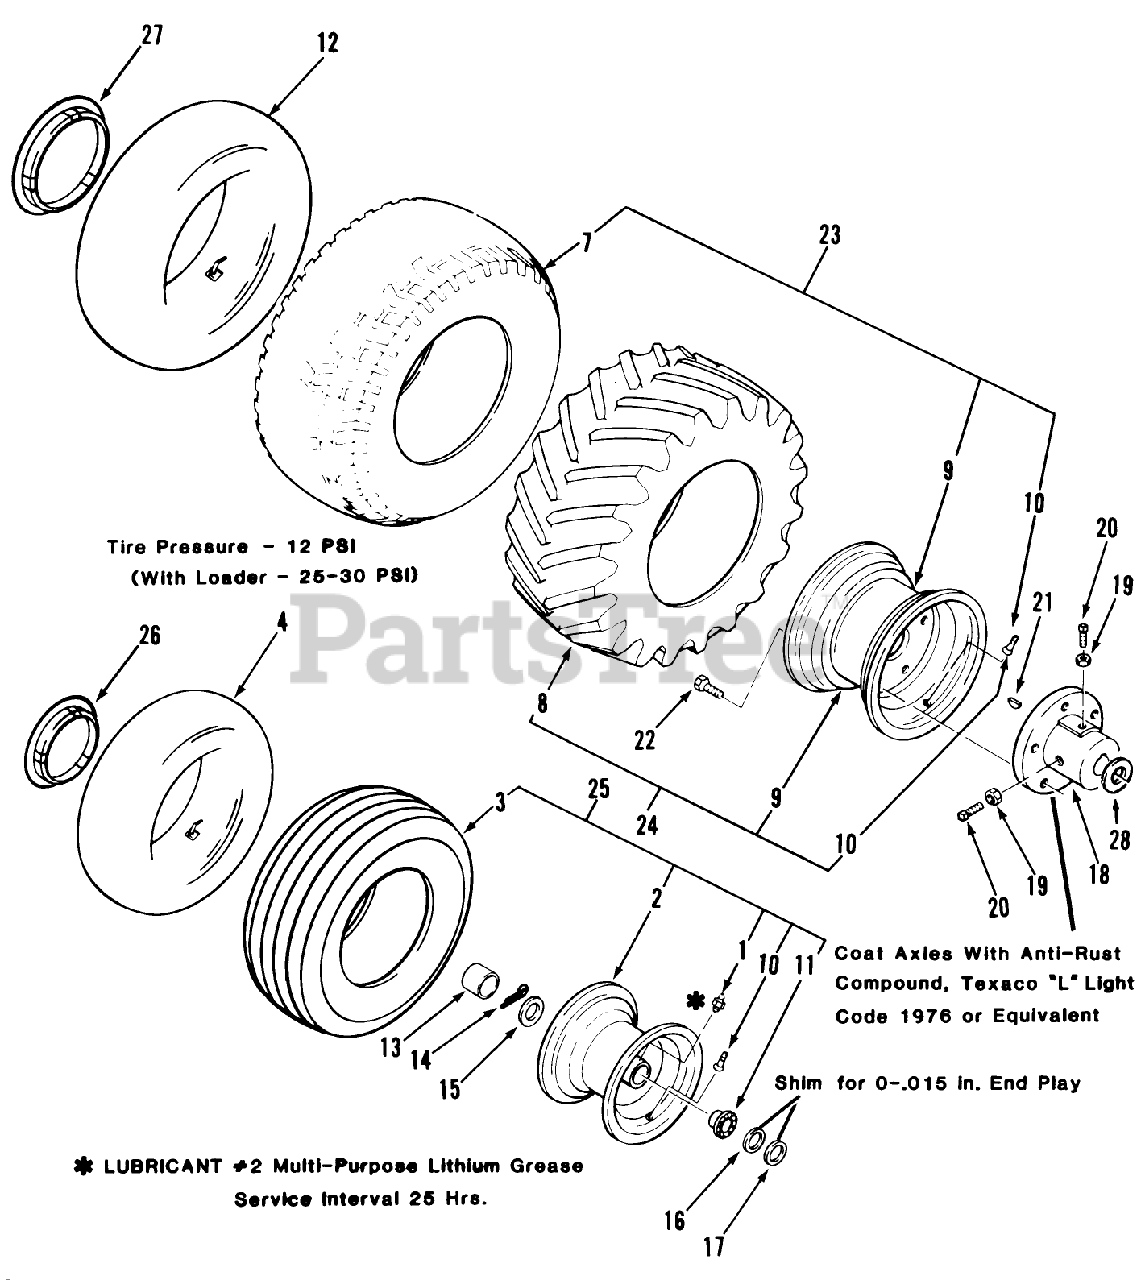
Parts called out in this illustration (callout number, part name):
1	ZERK-GREASE
9	WHEEL
9	RIM ASM
10	VALVE
11	BEARING-WHEEL
11	BEARING-RADIAL FLNGE
13	HUBCAP
14	COTTER PIN-4
15	WASHER-WHEEL
15	WASHER WHEEL
16	WASHER
17	WASHER-SHIM
21	KEY-WOODRUFF
23	Rear Wheel Tire Assy 312-A
23	ORDER COMPONENT PARTS
28	WASHER-THRUST
